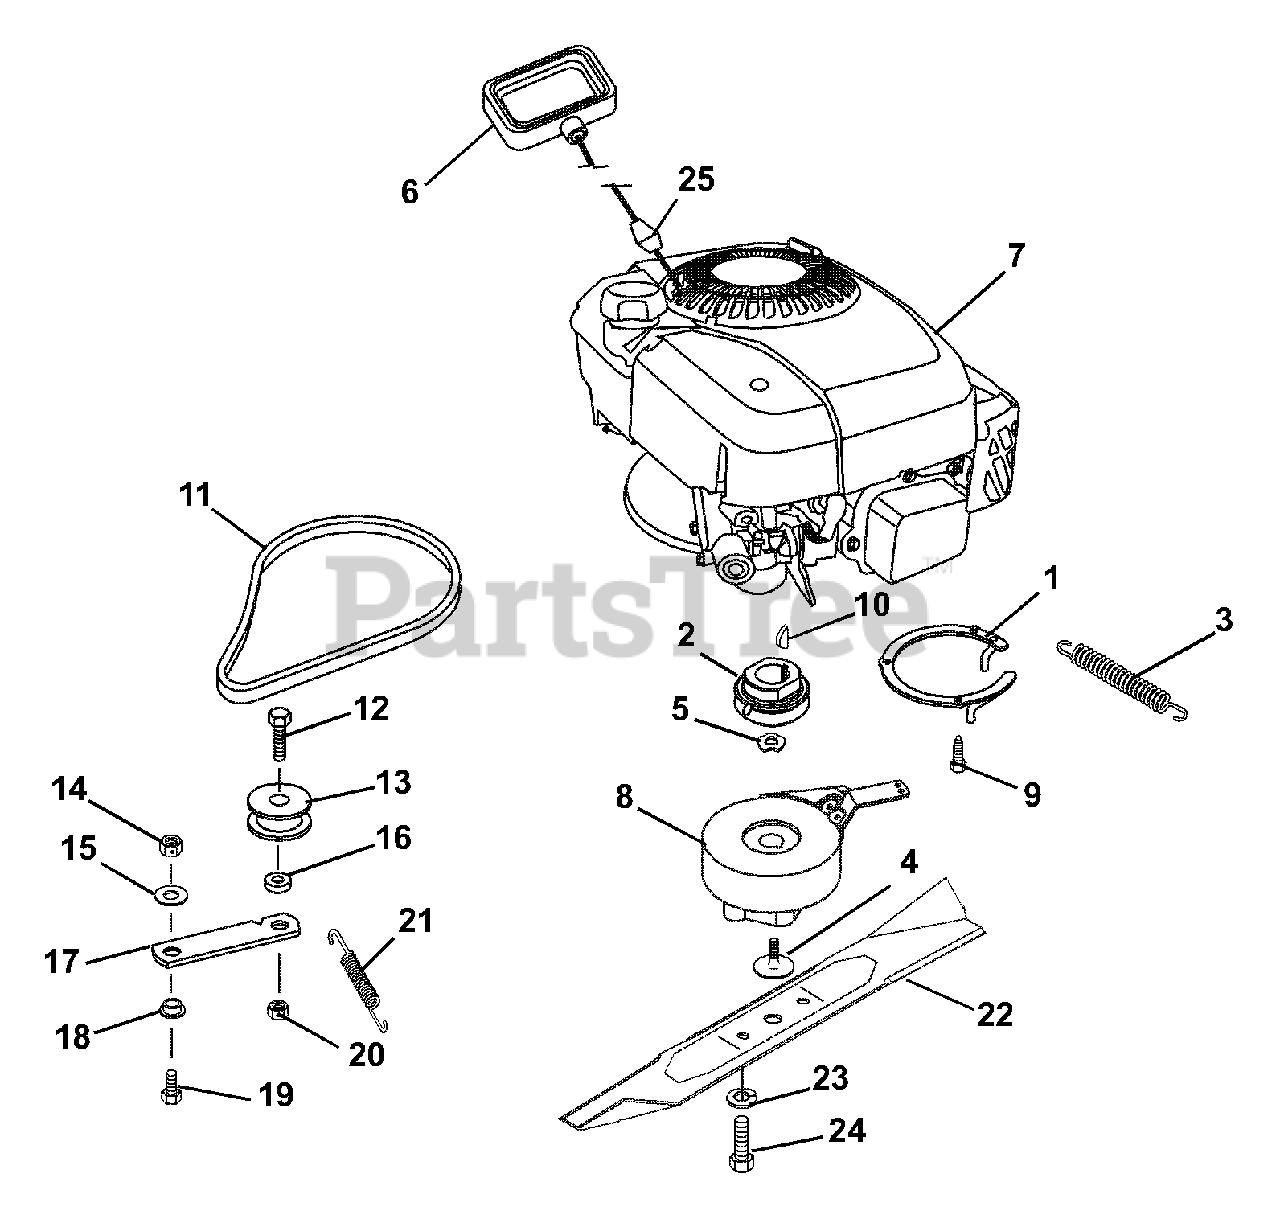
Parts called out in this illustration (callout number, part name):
1	BRACKET - SPRING RETAINER
2	PULLEY-SINTERED IRON LM
3	SPRG-TENS
4	SCR-SKH-SPECIAL .375-24X1.50
5	WASHER-WAVE .885X1.311X.125
6	HANDLE, RECOIL START
7	ENGINE, BRIGGS INTEK PRO BBC
8	BLADE BRAKE CLUTCH
9	@SCR-TAP .38-16X1.00 HWH TR YZ
10	KEY-WDRF .156X.625X.25 SAE 6
11	V-BELT, 3L-COGGED
12	@BLT-HEX .44-14X1.50 GR5 YWZC
13	IDLER-FLAT 1.75 X .47
14	@NUT-LK-CTR .31-18 YWZC
15	@WSHR-FL-STL.344X.688X.065YWZC
16	BSHG-SLV .469 X .750 X .430
17	IDLER ARM
18	BSHG-FLG .325X.501X.250X1.120
19	@BLT-HEX .31-18X.75 GR5 YWZC
20	@NUT-LK-CTR .44-14 YWZC
21	SG-TENS .043X.44X3.31 WLD 5.8
22	21" BLADE - BBC
23	@WSHR-LK .44X.109 REG YWZC
24	BLT-HEX M10 X 1.5X25 YWZC
25	ROPE STOP
